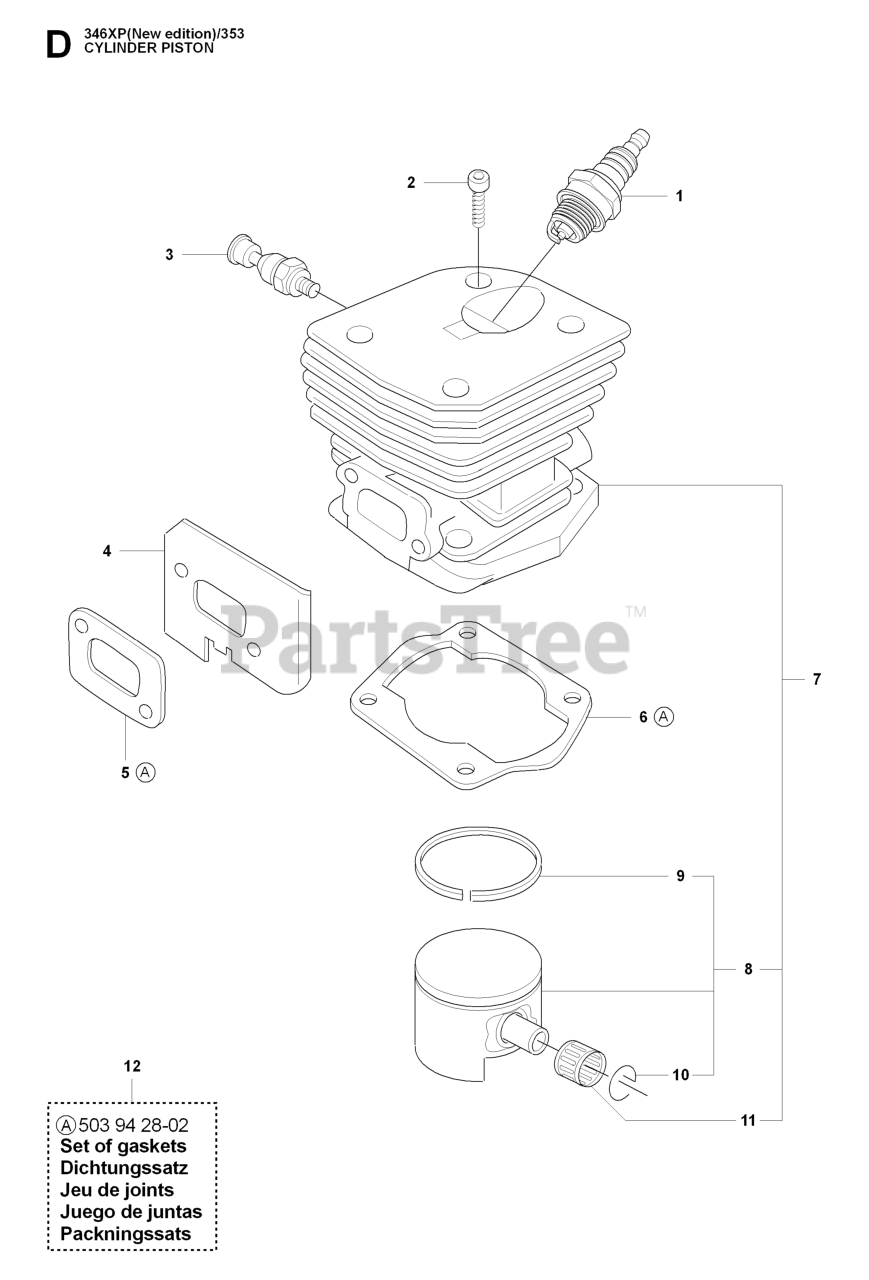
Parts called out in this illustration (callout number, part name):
1	SPARK PLUG RCJ7Y
2	SCREW MC6S 5X25
3	DECOMPRESSION VALVE
7	CYLINDER ASSY
7	CYLINDER
7	%CYLINDER
8	%PISTON
8	PISTON
8	PISTON ASSY
9	PISTON RING
9	%PISTON RING
10	LOCKING RING
11	SUPPORT BUSHING
12	GASKET SET
